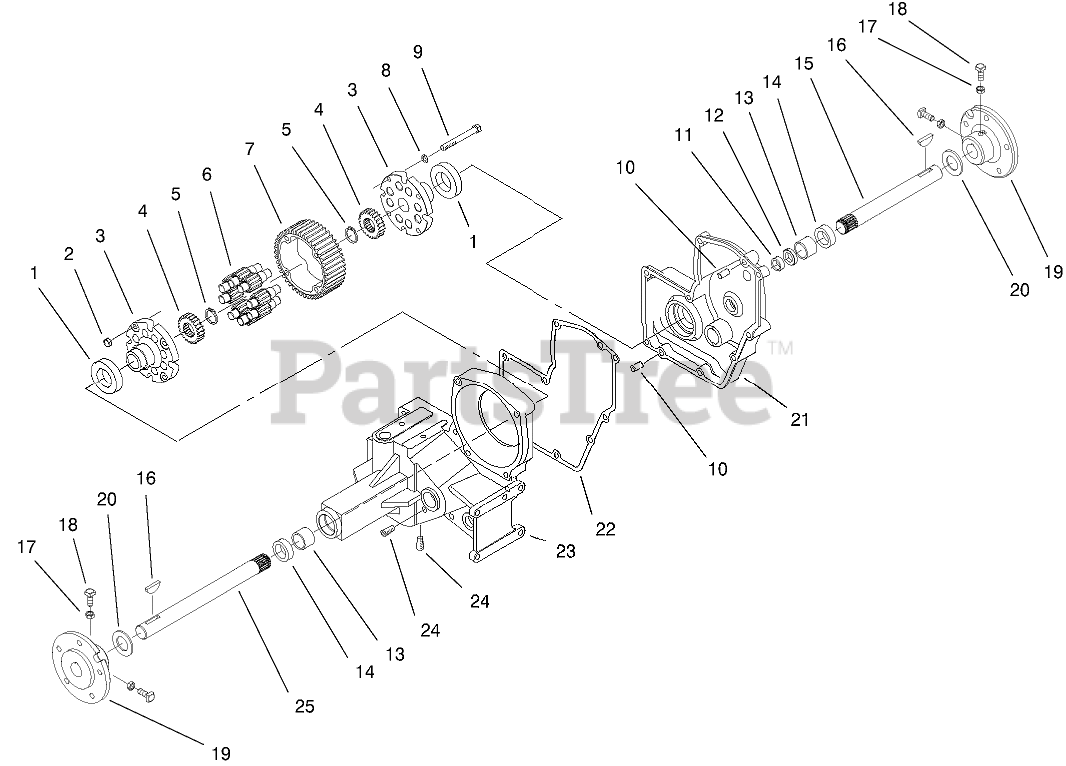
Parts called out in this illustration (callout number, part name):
1	BEARING-BALL
3	END CAP-DIFFERENTIAL
4	GEAR-AXLE DIFFERENTIAL
5	RING-SNAP
6	GEAR-PINION, 11T
7	GEAR-DIFFERENTIAL RING, 43T
8	WASHER
9	BOLT-HEX
10	PIN-LOCATING
11	NEEDLE BEARING
12	Seal
13	BEARING
14	SEAL-OIL
15	AXLE-REAR LH
16	KEY-WOODRUFF
17	NUT-JAM
18	SCREW-SET, SQH
19	Hub Rear
20	WASHER-THRUST
21	CASE TRANS LH
22	GASKET-TRANSMISSION
25	CASE-TRANS RH
26:1	GEAR 46T
26:2	PINION SHAFT
27	AXLE-REAR RH
